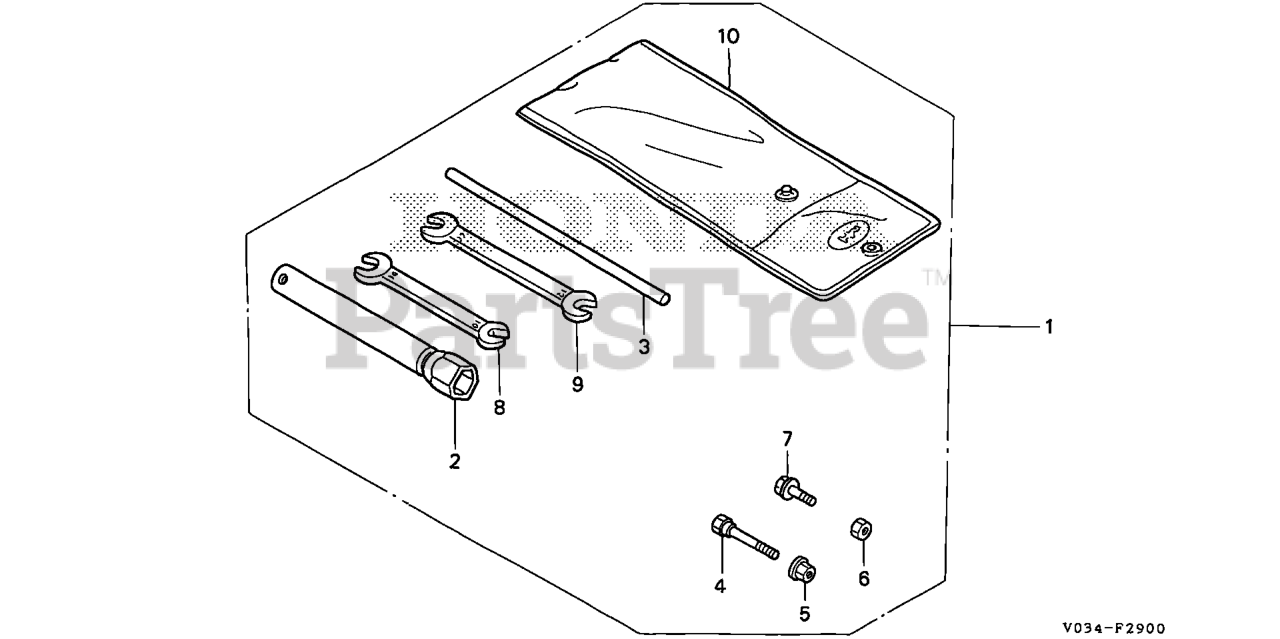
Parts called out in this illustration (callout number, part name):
1	TOOL KIT
1	TOOL KIT (NOT AVAILABLE)
2	WRENCH, SPARK PLUG (NOT AVAILABLE)
3	HANDLE, BOX WRENCH (NOT AVAILABLE)
4	BOLT, LOCK
5	NUT, SELF-LOCK (6MM)
6	NUT, HEX. (6MM)
7	BOLT, HEX. (6X16)
7	BOLT, FLANGE (6X16) Use from Engine SN 2056820.
8	WRENCH (10X14) (OPEN END)
9	WRENCH (12X17) (OPEN END) (NOT AVAILABLE)
10	BAG, TOOL
